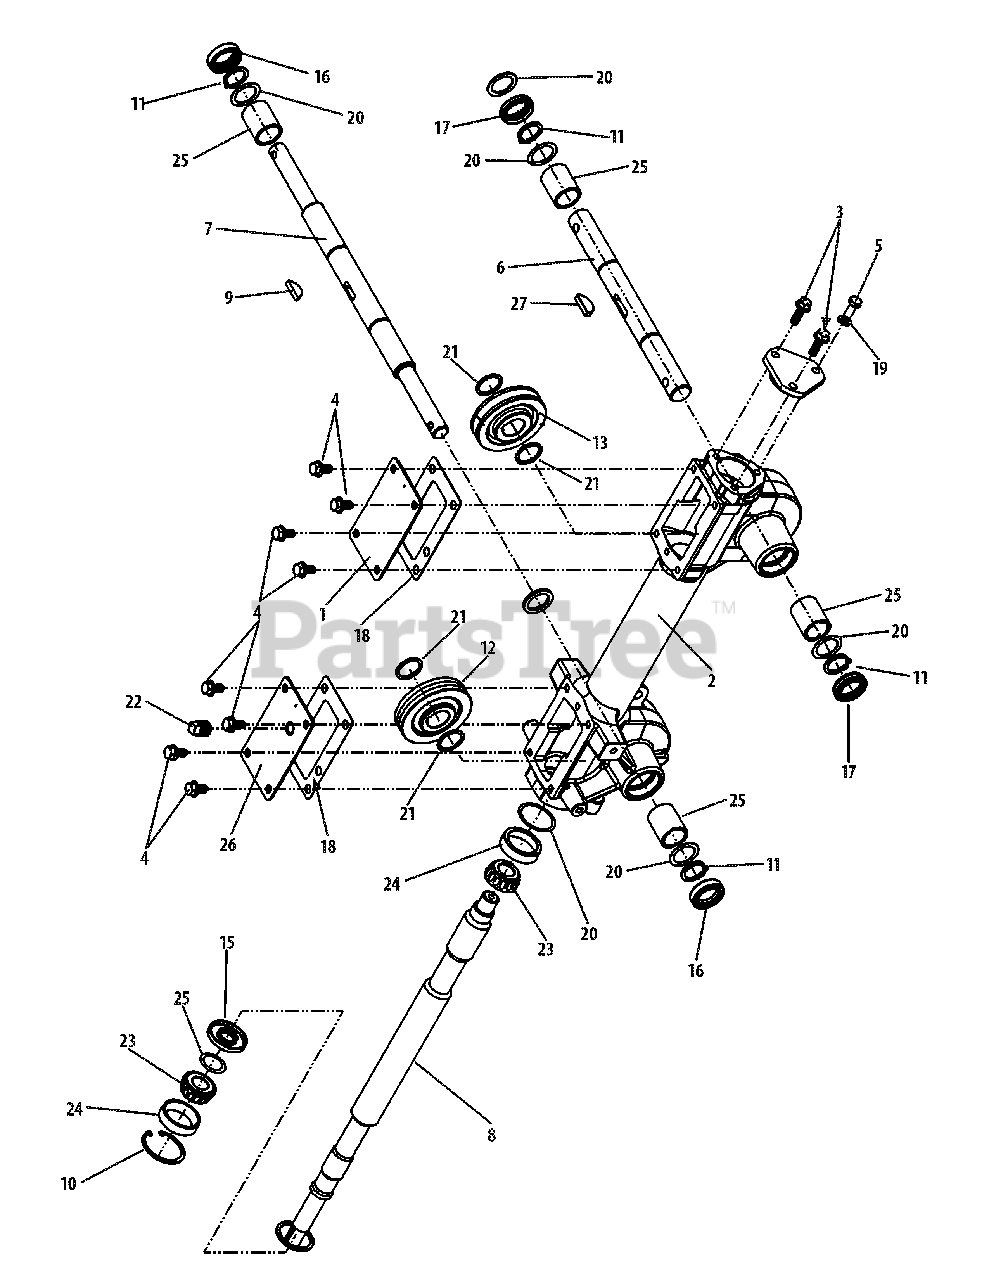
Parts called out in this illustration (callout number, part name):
1	Cover Housing
2	Transmission Housing
3	Hex Head Flange Screw
4	Hex Head Flange Screw
5	Hex Screw
6	Tiller Shaft
7	Wheel Shaft
8	Drive Shaft
9	Hi-Pro Key
10	Retaining Ring
11	Retaining Ring
12	Worm Gear, 61T
13	Worm Gear, 30T
14	Rear Bearing Cover
15	Oil Seal, .75 x 1.783
16	Oil Seal, 1.0 x 1.499
17	Oil Seal, 1.0 x 1.5
18	Gear Housing Gasket
19	Lock Washer
20	Flat Washer, 1.375 x 1.015 x .062
20	Flat Washer, 1.5 x 1.75 x .01
20	Flat Washer, 1.5 x 1.75 x .03
20	Flat Washer, 1.5 x 1.75 x .005
20	Flat Washer, 1.5 x 1.75 x .062
20	Flat Washer, 1.25 x .75 x .06
20	Flat Washer, 1.015 x 1.375 x .03
20	Flat Washer, 1.015 x 1.375 x .015
20	Flat Washer, 1.015 x 1.375 x .01
20	Flat Washer, 1.015 x 1.375 x .005
21	Flat Washer, 1.015 x 1.234 x .062
23	Cone Bearing
24	Cup Bearing
25	Bushing, 1.005 x 1.25 x 1.5
26	Transmission Cover
27	Woodruff Key, .25 x 1.12
